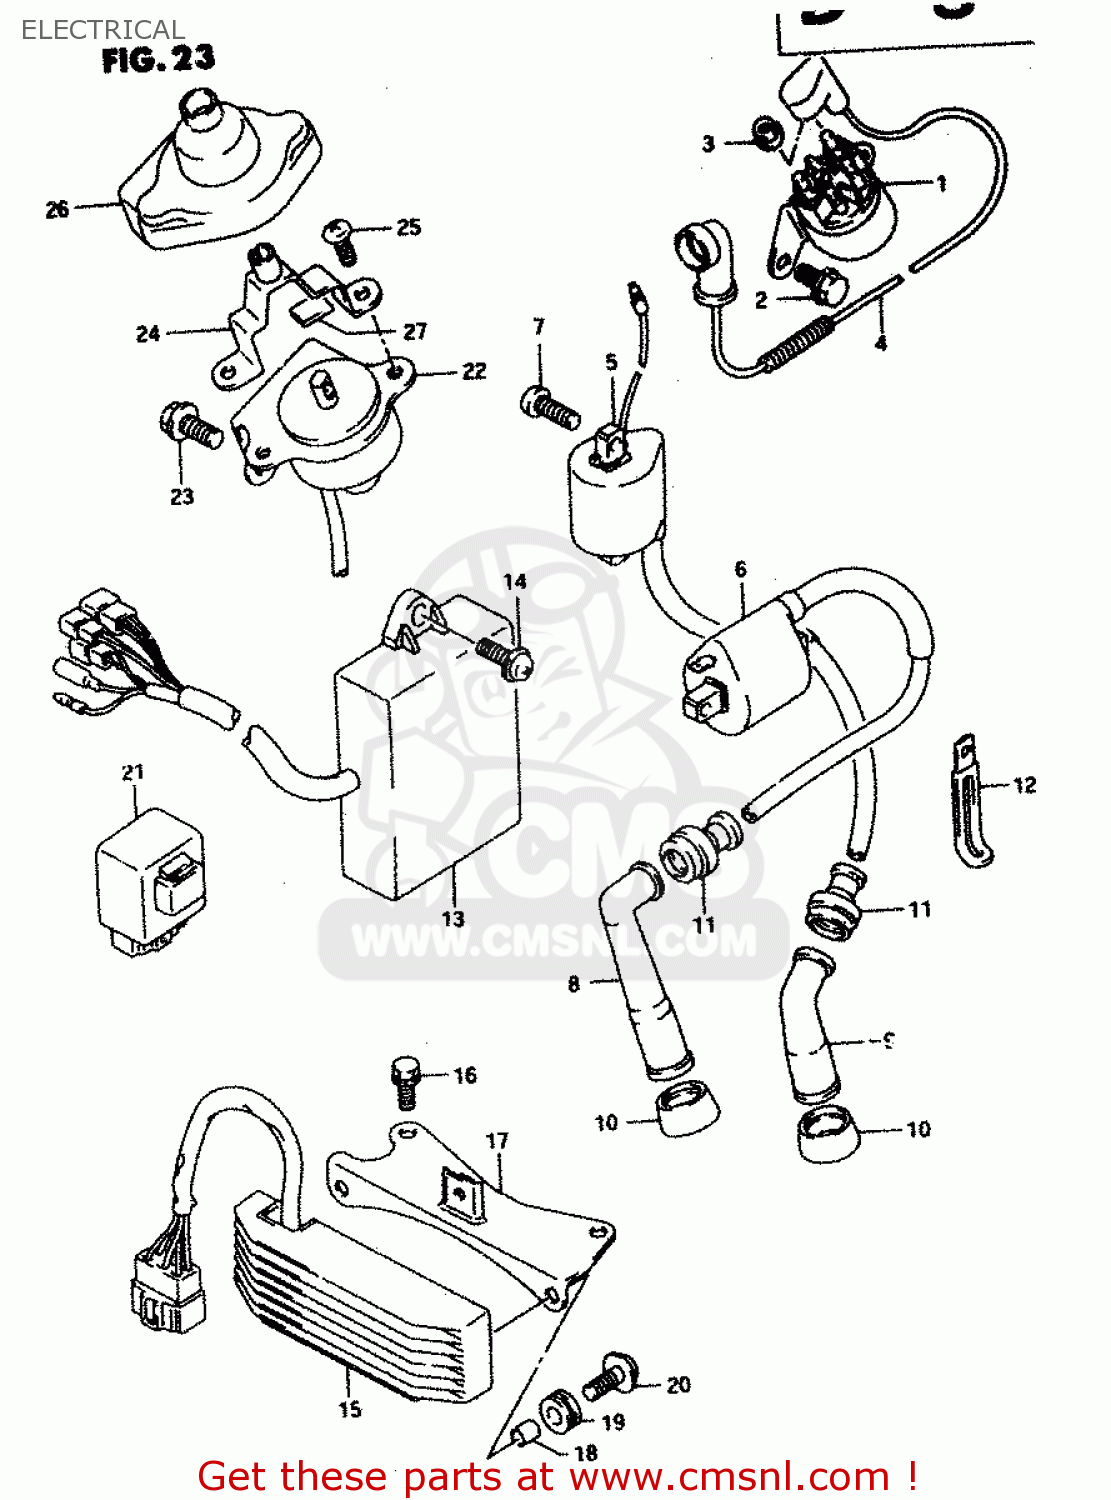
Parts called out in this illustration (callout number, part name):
1	RELAY ASSY,STARTING MOTOR
2	BOLT
3	NUT
4	WIRE,STARTER MOTOR LEAD
5	COIL ASSY,IGNITION
6	COIL ASSY,IGNITION
7	SCREW, 6X20
8	CAP ASSY,SPARK PLUG
9	CAP,SPARK PLUG
10	SEAL,SPARK PLUG CAP
11	SEAL,HIGH TENSION CORD
12	CLAMP
13	CDI UNIT
14	SCREW
15	RECTIFIER ASSEMBLY
16	BOLT
17	BRACKET,RECTIFIER
18	SPACER (6.1X8X9.5)
19	CUSHION
20	SCREW(6X20)
21	CONTROL UNIT,DECOMP
22	SOLENOID ASSY,DECOMP
23	BOLT
24	HOLDER,DECOMPRESSION CABLE
25	SCREW
26	COVER,DECOMP
27	CUSHION
